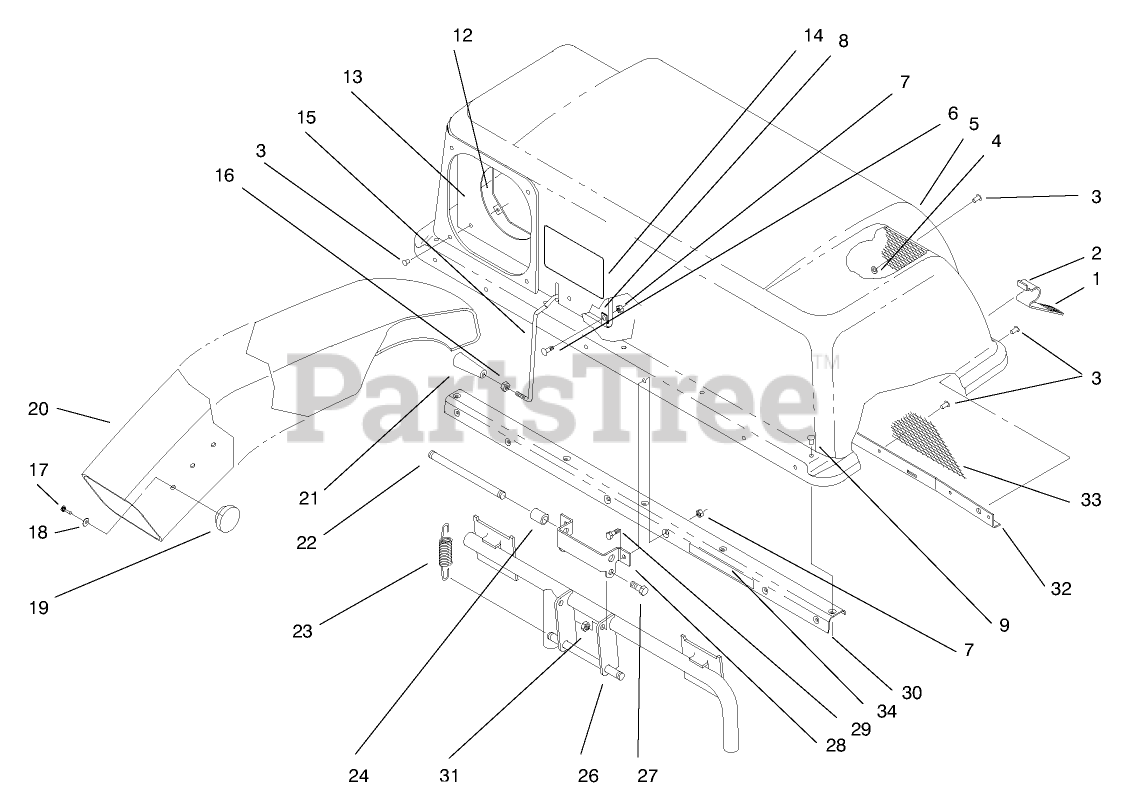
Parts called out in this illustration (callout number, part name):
3	RIVET-BLIND
4	WASHER-FLAT
5	TOP-BAGGER
6	SCREW-PPH
7	NUT-LOCK, NI
8	CLAMP
12	CLAMP-SEAL
13	SEAL-CHUTE
14	DECAL
15	FEELER-FILL, BAG
16	NUT-JAM
17	SCREW-PPHTF
18	WASHER-PLAIN
20	CHUTE-DISCHARGE
21	HANDLE-TAPERED
22	PIN-SPRING
23	SPRING-EXTENSION
24	SPACER
27	SCREW-HH
29	SCREW-HH
30	STIFFENER ASM
31	NUT-LOCK, NI
33	SCREEN-BAGGER
34	DECAL-CAUTION
